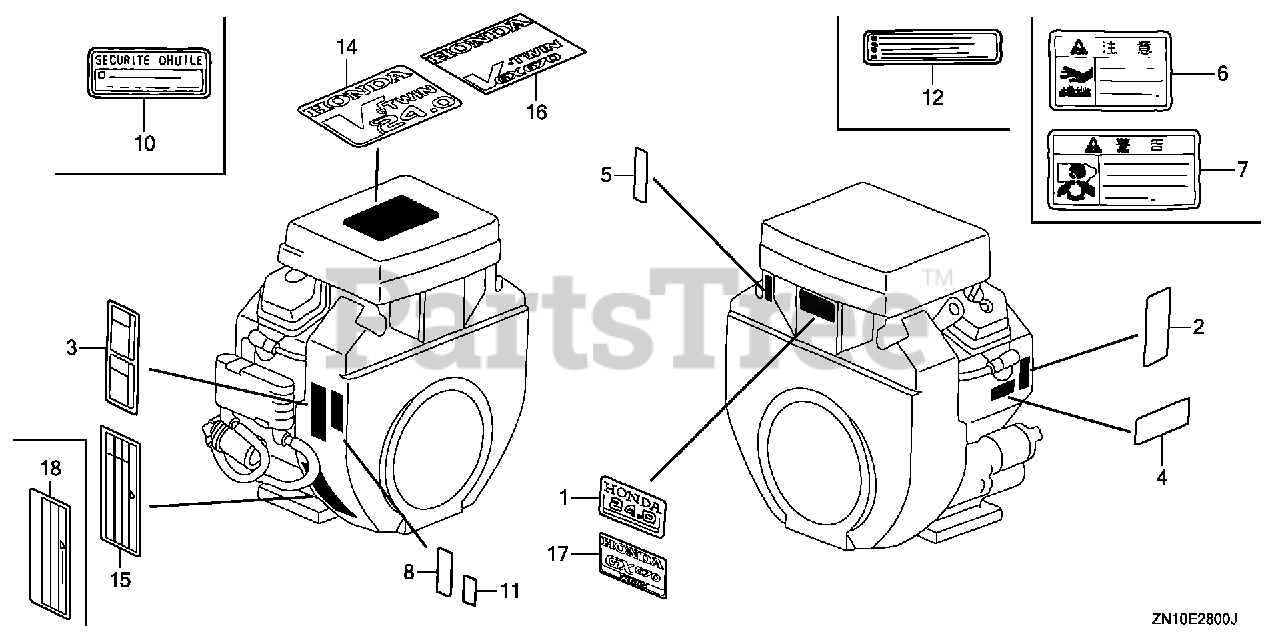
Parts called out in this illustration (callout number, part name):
1	EMBLEM (24.0)
1	EMBLEM (GX670)
2	LABEL, SPECIFICATION (GX670)
4	MARK, OIL ALERT (ENGLISH)
